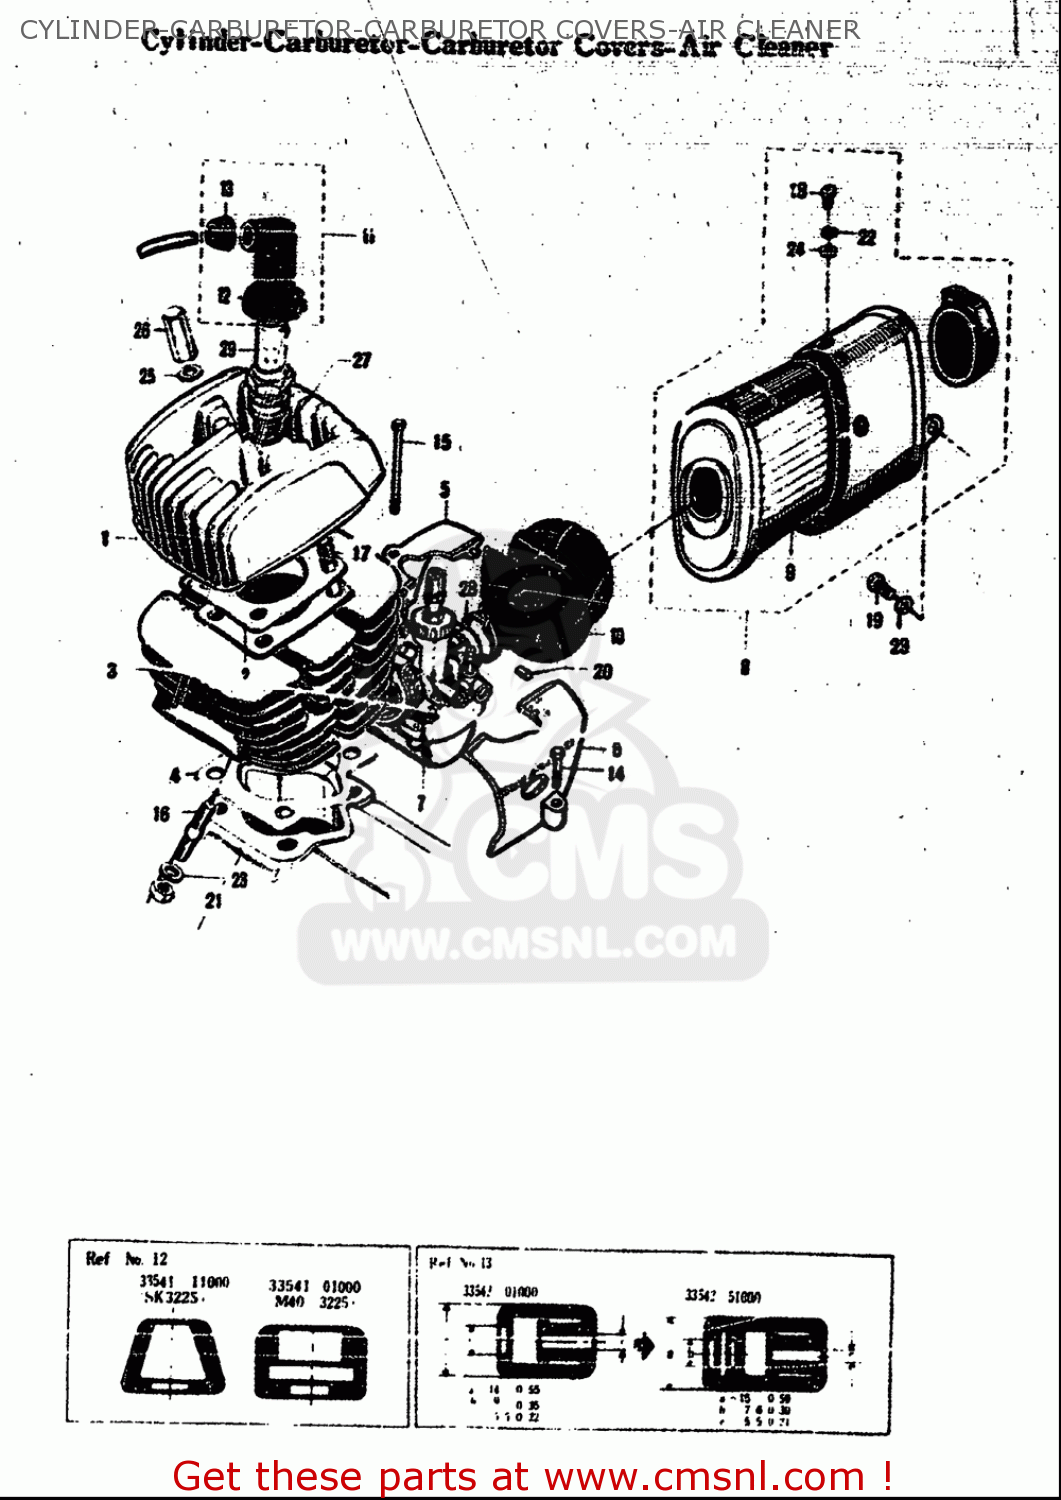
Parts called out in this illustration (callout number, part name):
2	CYLINDER HEAD GASKET
15	BOLT(6X70)
17	STUD 6X95
21	NUT
22	WASHER,LOCK
23	WASHER,LOCK
24	WASHER
25	WASHER
26	NUT (6MM)
27	GASKET(14X19.2X2) (NAS)
